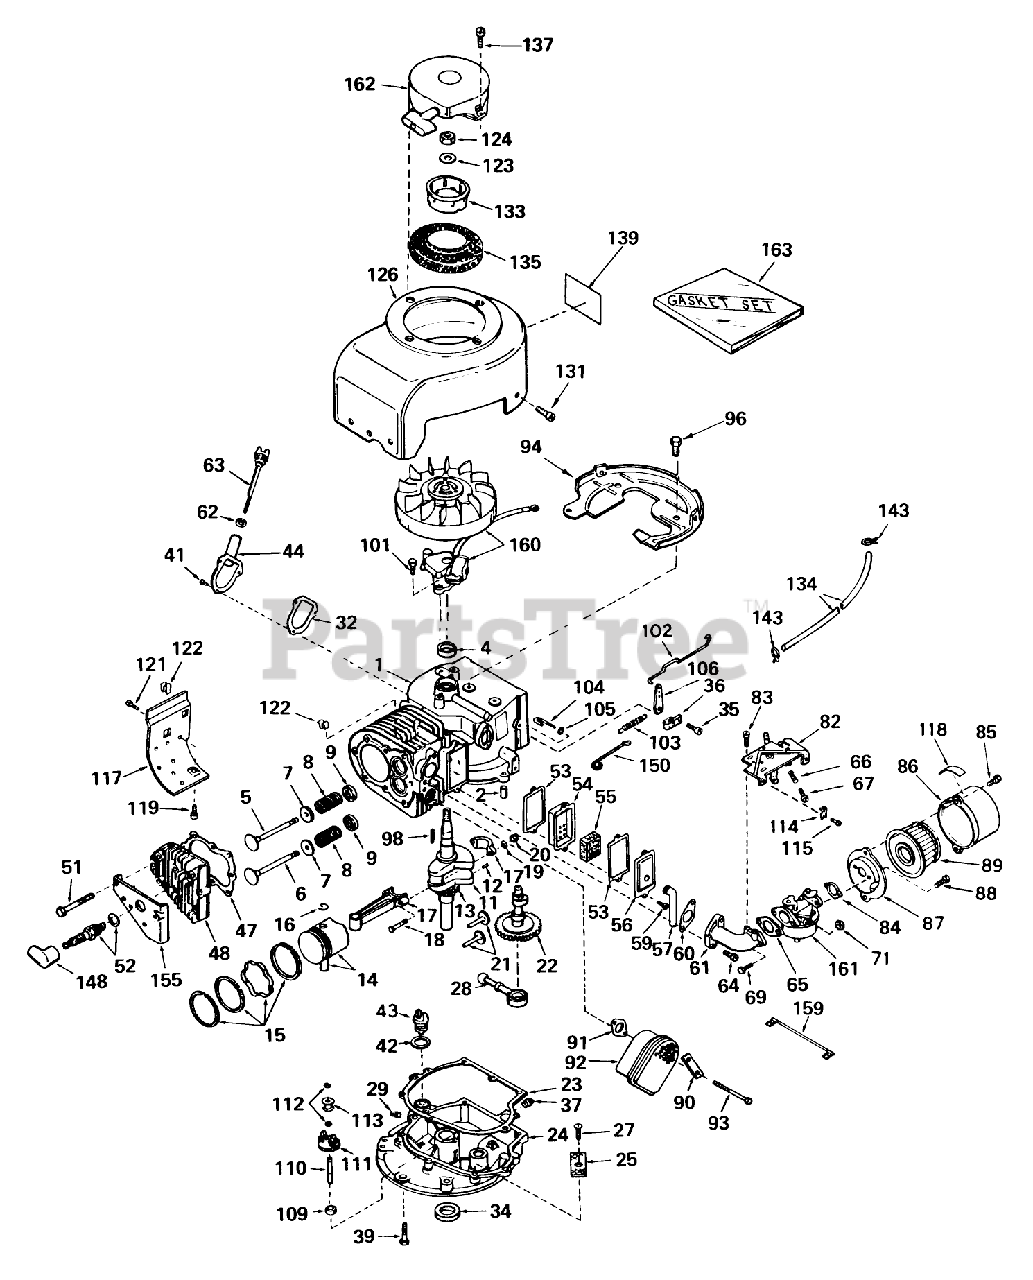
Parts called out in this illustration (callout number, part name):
1	Cylinder Assy. (Incl. Nos. 2 4)
2	Pin-Dowel
4	Seal, Oil
5	Valve, Intake, Standard (Incl. No. 9)
5	Valve, Exhaust (1/32" oversize)(Incl. No. 9)
6	Valve, Exhaust, Standard (Incl. No. 9)
6	Valve, Exhaust, 1/32" Oversize (Incl. No. 9)
7	Cap-Spring, Valve
8	Spring-Valve
9	Keeper-Spring, Valve
11	Crankshaft Assy. (Incl. # 12 13)
12	Pin, Groove
13	Gear-Crankshaft
14	Piston Pin Assy. (Standard)(Incl. 2 of No. 16)
14	Piston Pin Assy. (.010 oversize)(Incl. 2 of No. 16)
14	Piston Pin Assy. (.020 oversize)(Incl. 2 of No. 16)
15	Ring Set, Piston (Std.)
15	Ring Set, Piston (.010 Oversize)
15	Ring Set, Piston (.020 oversize)
17	Rod Assy., Connecting (Incl. Nos. 18, 19 20)
18	Bolt, Connecting Rod
19	Washer
21	Lifter Valve
22	Screw
23	Gasket-Cover, Cylinder
24	Flange Assy., Mounting (Incl. #25, 27, 34, 37 110)
25	Screen-Oil Filter
27	Screw
28	Pump, Oil
29	Plug-Pipe (Internal Hex, 1/4-18)
32	Gasket, Filler tube
34	Seal-Oil
35	Screw
36	Clamp-Lever, Governor
37	Plug-Drain, Oil (SQH 1/4-18)
39	Screw (1/4-20 x 1-1/4)
41	Screw
42	Gasket
43	Plug-Fill, Oil
44	Tube, Oil Filler
47	Gasket-Head, Cylinder
48	CYLINDER HEAD
51	Screw Hex Hd. Cap
52	Plug, Spark (J17LM or equiv.)
53	Gasket-Breather
54	Body-Breather
55	Element-Breather
56	Cover-Valve
57	Tube-Breather
59	Screw
60	Gasket-Intake
61	Pipe, Intake
62	Gasket
63	Dipstick, Oil (Incl. No. 62)
64	Screw (T-30, 5/16-18x1-3/32)
65	Gasket
66	Spring-Compression
67	Screw
71	Nut and Lock Washer (1/4-28)
82	Control Assy., Speed (Incl. Nos. 161 162)
83	Screw (10-24 x 9/16)
84	Gasket
85	Screw
86	Body
87	Bracket
88	Screw (10-32 x 1/2)
89	Element
90	62513 SNWTHWR W/284
91	Gasket Exhaust
92	Muffler
93	Screw Hex Hd.
94	Baffle Blower Housing
96	Screw (1/4-20x19/32)
98	Key, Flywheel
101	Screw
102	Link Governor
103	Spring Governor
104	Rod, Governor (Incl. Nos. 146)
105	Washer-Flat
106	Lever-Governor
109	Spacer
110	Shaft, Governor
111	Governor Gear ASM
112	Ring-Retaining
113	Spool-Governor
114	Conduit
115	Screw (10-32 x 3/8)
117	Emnsion, Blower Housing
118	Decal
119	Screw
121	Screw
122	51004 GIL ROTARY TI
123	Washer
126	Housing, Blower
131	Screw, Hex Hd.
133	Cup-Starter
134	Line-Fuel
135	Screen, Air
137	Screw
139	480B GIL SNWTHWR O/
143	Clamp-Line, Fuel
148	Cover-Spark Plug
150	Link Governor Spring
155	Cover-Head, Cylinder
159	Wire, Ground
160	Magneto
161	Carburetor
162	Starter, Rewind
163	Gasket Set (Incl. items marked*)
